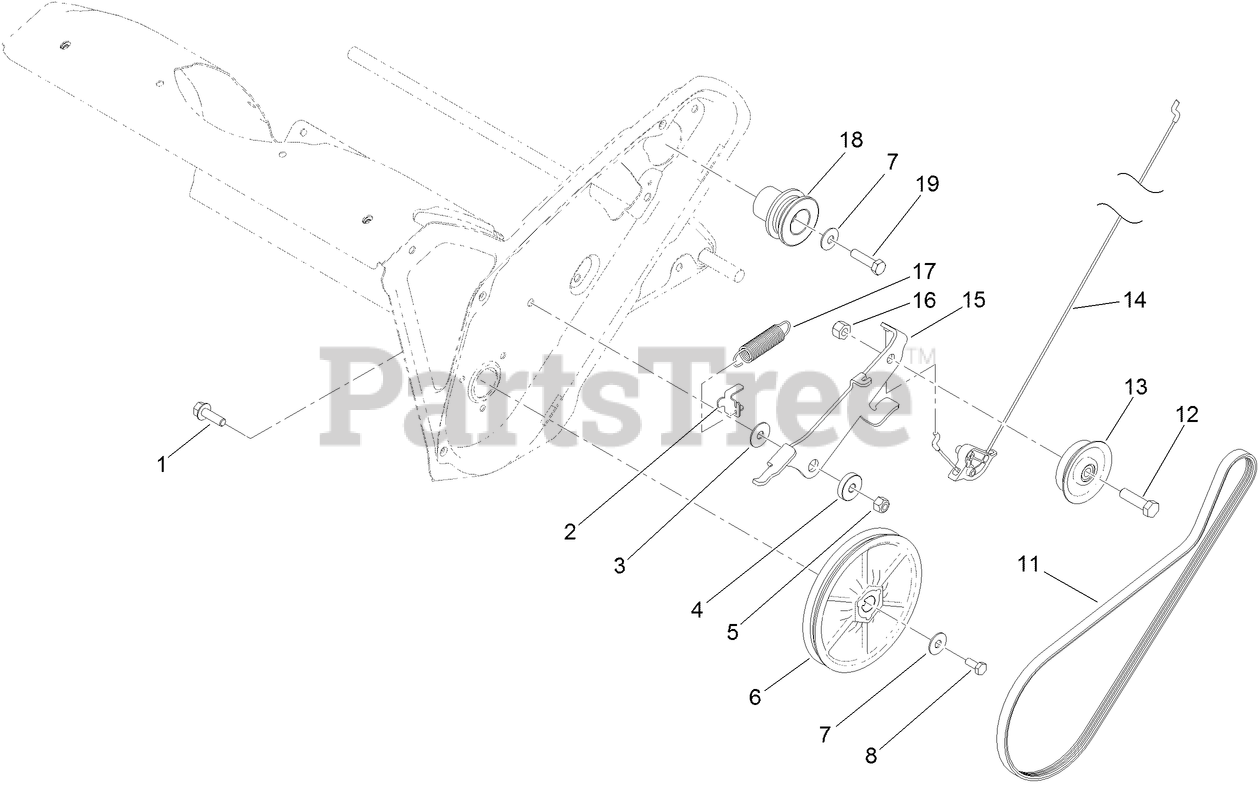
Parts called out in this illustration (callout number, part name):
1	SCREW-HHF
3	WASHER
4	BUSHING-PIVOT
5	NUT-LOCK, NI
6	ROTOR PULLEY ASM
7	WASHER-BELLEVILLE
8	SCREW-HH
11	BELT-DRIVE
12	SCREW-HH
13	PULLEY-IDLER
14	CABLE-CLUTCH
15	ARM-IDLER
16	NUT-LOCK, CONE
17	SPRING-EXTENSION
18	PULLEY-ENGINE
19	SCREW-HH
